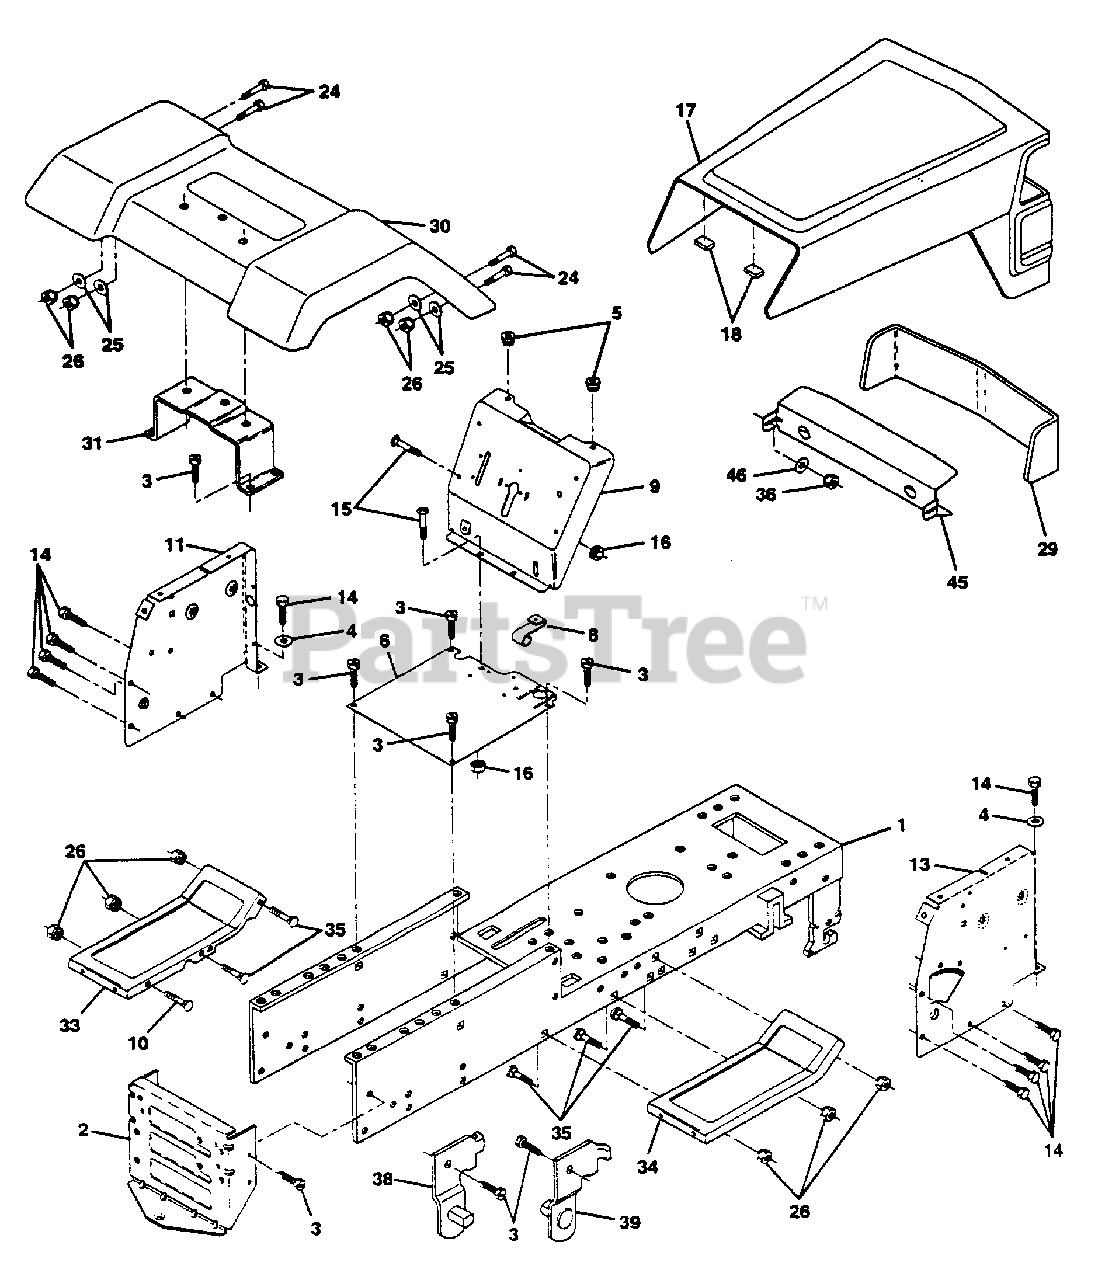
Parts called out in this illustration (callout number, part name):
1	CHASSIS.WLD.11GA
3	SCREW
4	WASHER
8	"CLIP,INSULATOR"
9	DASH.SLKSC.LT.1PC
11	DASH PANEL LH
14	SCREW LT
15	SCREW
17	HOOD/GRILLE.ASM.
24	BOLT
25	WASHER
26	NUT
28	GRILLE.RALLY.BAR.
29	LENS SERVICE KIT
31	BRKT FENDER
33	FOOTREST.LH.PERF.
34	FOOTREST.RH.PERF.
35	BOLT
36	PAL NUT LT
38	BRACKET ASM LH
39	BRACKET ASM RH
46	RETAINER
